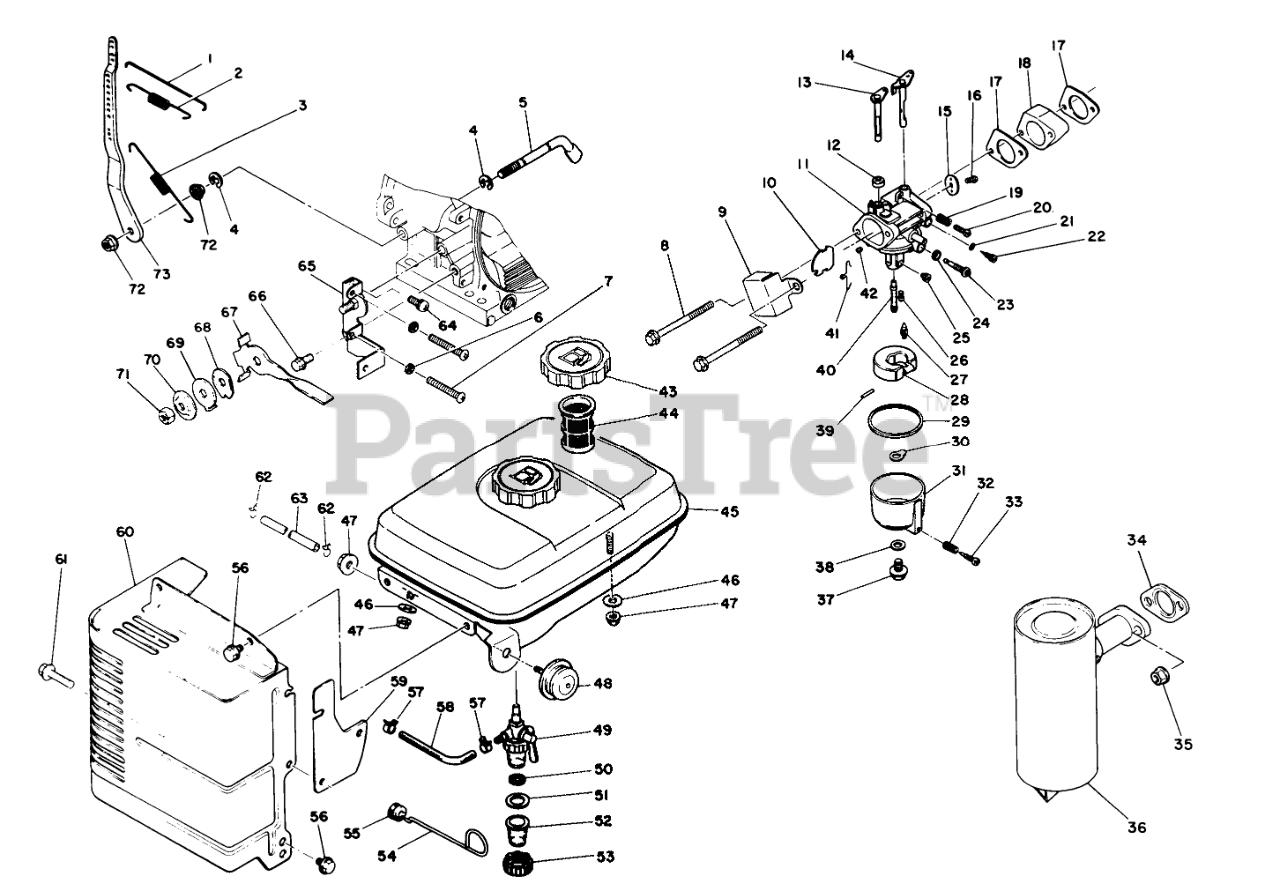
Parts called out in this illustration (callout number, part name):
1	GOV.ROD
2	SPRING-ROD
3	SPRING
4	SNAP RING
5	GOV SHAFT
7	SCREW
9	COVER
10	VALVE
11	Carburetor Assembly (Incl. Ref. #10-16, 33 & 37-42)
13	SHAFT
14	THROTTLE SHAFT
15	THROTTLE VALVE
16	SCREW
17	CARB GASKET
18	INSULATOR
19	SPRING
20	SCREW
21	O - RING
22	Valve-Needle (Incl. Ref. #21)
23	SLOW JET
24	GASKET
25	MAIN JET
26	SCREW
27	VALVE
28	FLOAT
29	GASKET
30	GASKET
31	Bowl-Float (Incl. Ref. #32 & 33)
32	SPRING
33	SCREW
34	GASKET
36	MUFFLER
38	GASKET
39	FLOAT PIN
40	MAIN NOZZLE
42	BREATHER
43	FUEL TANK CAP
44	FUEL FILTER
45	Fuel Tank Assembly (Incl. Ref. #43, 44 & 46)
46	GASKET
49	Petcock-Fuel (Incl. Ref. #50-53)
50	SCREEN
51	GASKET
55	GROMMET
59	COVER
60	COVER
62	CLAMP
64	SCREW W/WASHER
65	BRACKET
67	LEVER
68	LEAF SPRING
69	WASHER
70	WASHER
73	GOV.LEVER
